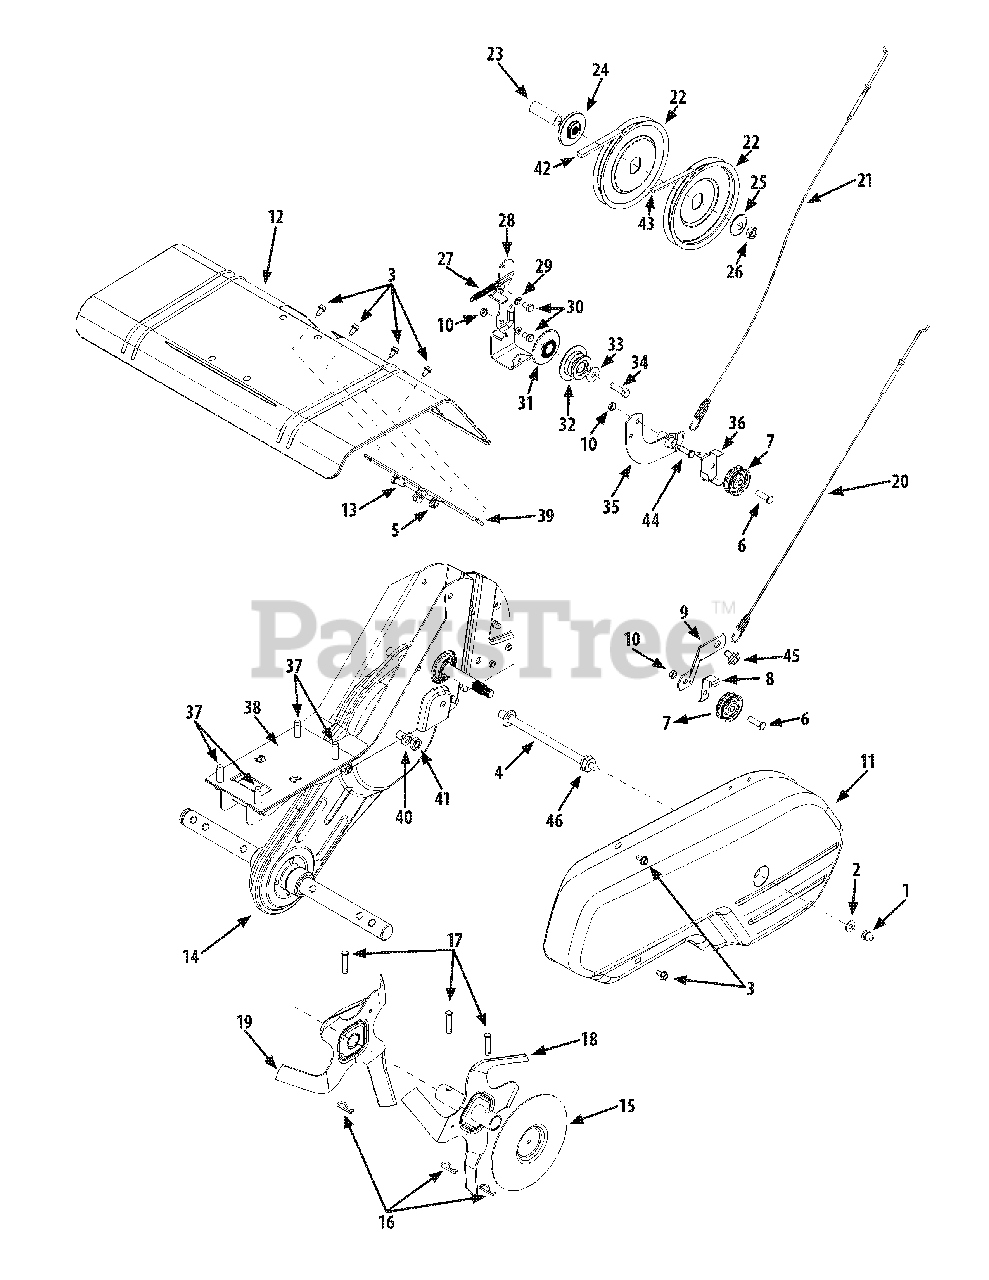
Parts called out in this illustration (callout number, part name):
1	Hex L-Stop Nut, 1/4-28
2	Flat Washer, 266" x .625"
3	Hex Washer TT-Tap Screw, 1/4-20 x .5"
4	Belt Cover Bolt
5	Hex Flange Top L-Nut, 5/16-18
6	Hex Head Screw, 3/8 -16 x 1.25"
7	Flat Idler Pulley, 2.12"
8	Idler Belt Keeper
9	Idler Bracket
10	Hex Center Jam Nut, 3/8-16
11	Belt Cover
12	Tine Shield
13	Hex Head Cap Screw, 5/16-18 x .75"
14	Chain Case Assembly Complete
15	Outer Disc Plate Assembly
16	Internal Cotter Pin
17	Clevis Pin
18	Outer Tine Assembly, Left
18	Outer Tine Assembly, Right
19	Inner Tine Assembly, Left
19	Inner Tine Assembly, Right
20	Forward Clutch Cable
21	Reverse Clutch Cable
22	Flat Pulley, 6"
23	Spacer, .64" x 2.4"
24	Pulley Mounting Adapter
25	Bell Washer, 525" x 1.5"
26	Hex Jam Nut, 1/2-20
27	Return Spring
28	Reverse Bracket
29	Lock Washer, 5/16
30	Hex Bolt, 5/16-24 x .625"
31	Engine Inner Pulley
32	Reverse Engine Pulley
33	Bell Washer, .396" x 1/14"
34	Hex Bolt, 3/8 -24 x 1.00"
35	Reverse Arm Assembly
36	Reverse Belt Keeper
37	Hex L-Washer TT-Tap,3/8-16 x 1.25"
38	Engine Plate
39	Tine Shield Bracket
40	L-Washer, 7/16"
41	Hex Nut, 7/16-20
42	Forward Drive Belt, 1/2 x 41.9"
43	Reverse Drive Belt, 3/8 x 45.68"
44	Shoulder Screw, .498 x 1.445
45	Shoulder Screw, .560 x.165
46	Flangelock Nut, 5/16 - 18
